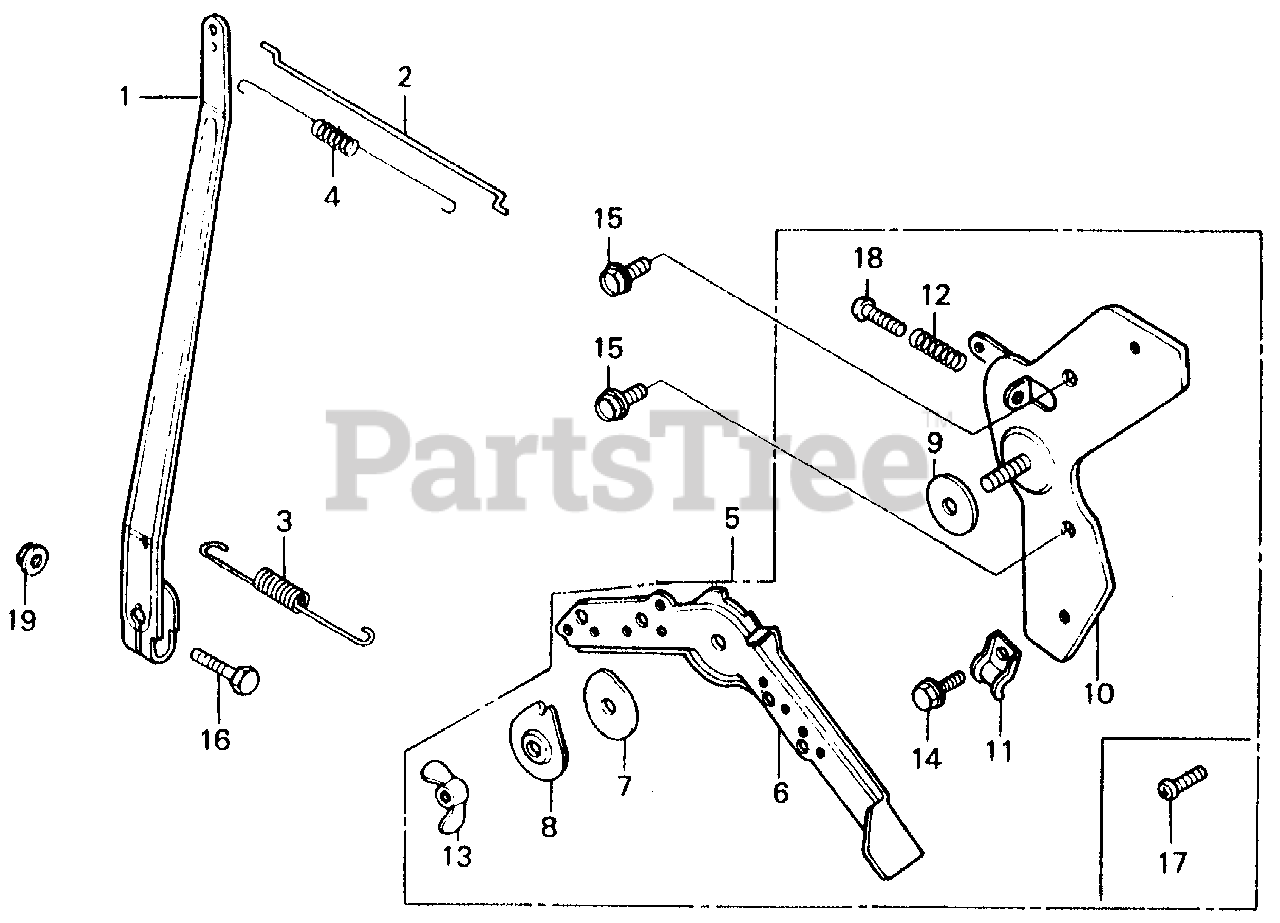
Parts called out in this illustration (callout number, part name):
1	ARM, GOVERNOR
2	ROD, GOVERNOR
3	SPRING, GOVERNOR
4	SPRING, THROTTLE RETURN
5	CONTROL ASSY.
6	LEVER, CONTROL
7	SPRING, LEVER
8	WASHER, CONTROL LEVER
9	SPACER, CONTROL LEVER
10	BASE, CONTROL LEVER
11	HOLDER, CONTROL CABLE
12	SPRING, CONTROL ADJUSTING
13	WINGNUT (6MM)
14	BOLT, FLANGE (5X10)
15	BOLT, FLANGE (6X12) (CT200)
16	BOLT, HEX. (6X20)
17	SCREW, PAN (5X10)
18	SCREW, PAN (5X22)
19	NUT, FLANGE (6MM)
